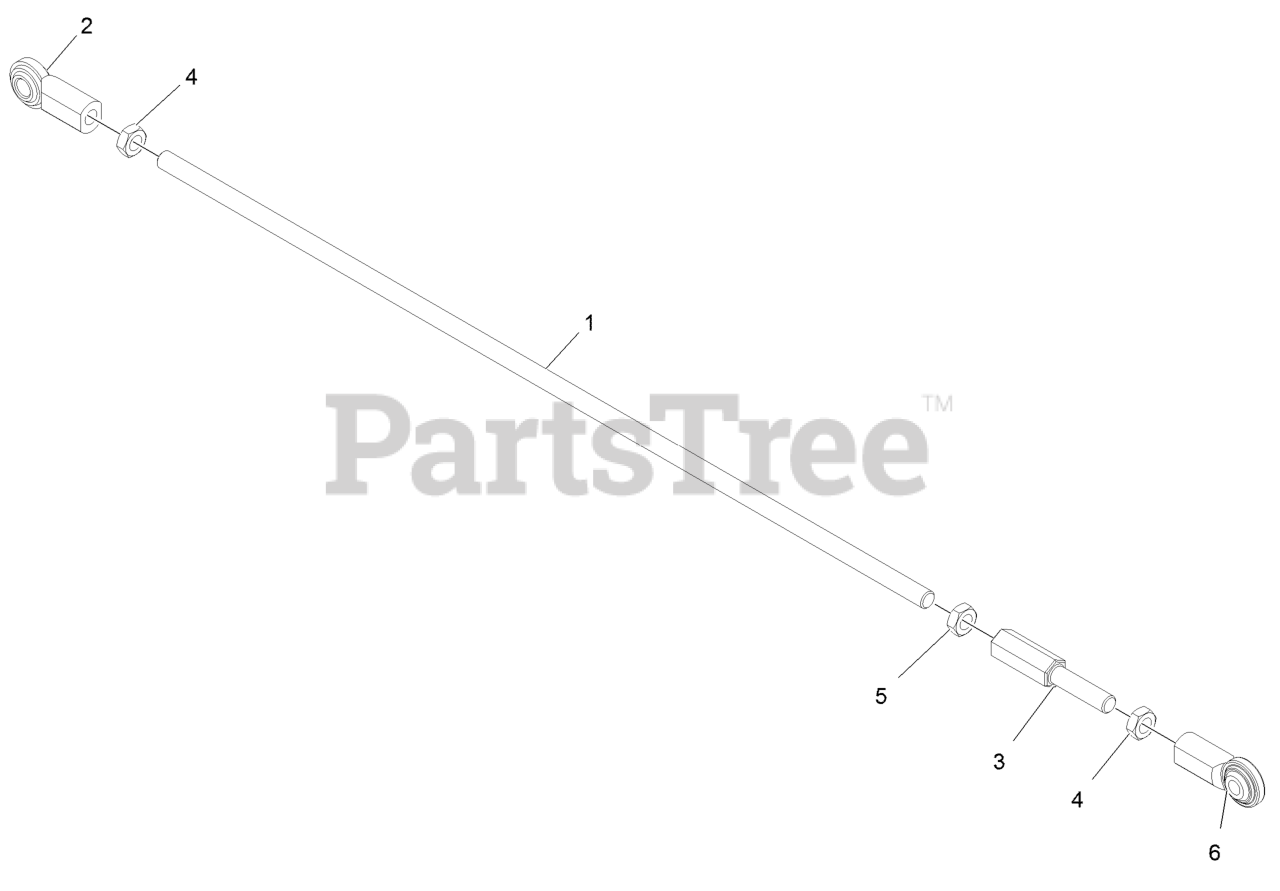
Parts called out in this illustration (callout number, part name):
1	LINKAGE, MOTION
2	JOINT-BALL, END
3	ROD-ADJUSTMENT
4	NUT-HJ
5	NUT-HEX JAM, LH
6	JOINT-BALL, END
